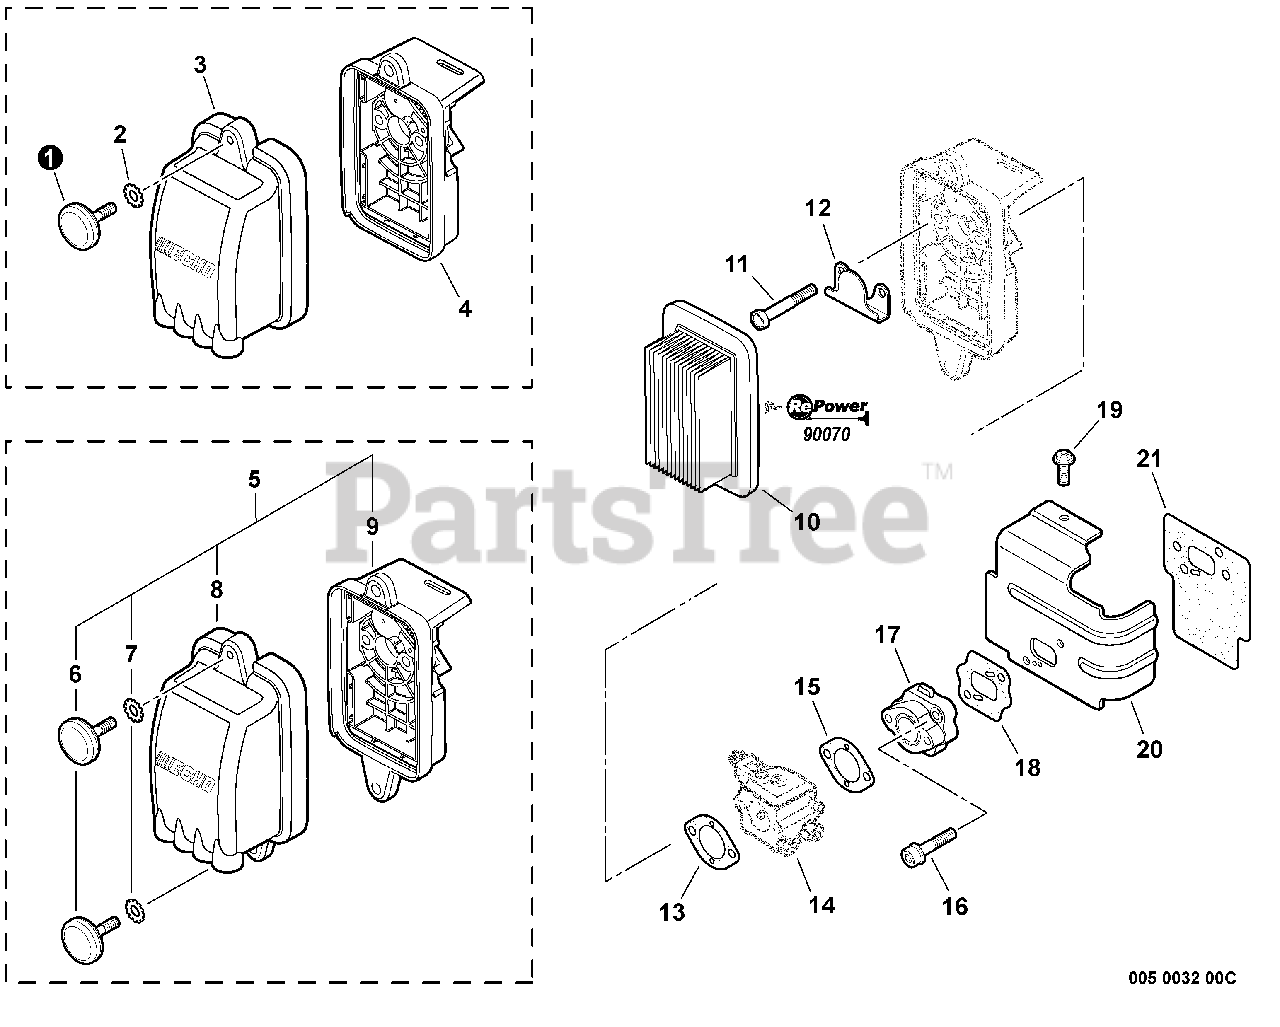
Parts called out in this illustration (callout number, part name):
1	THUMBSCREW
3	COVER, AIR FILTER
4	AIR FILTER CASE ASSY
5	FILTER KIT, AIR
6	THUMBSCREW
8	COVER, AIR FILTER
9	CASE ASSY, AIR FILTER
10	FILTER, AIR
11	BOLT 5×60
12	PLATE, PREVENT
13	GASKET, INTAKE
14	CARBURETOR
15	GASKET
16	INSULATOR, INTAKE
17	BOLT 5×25
18	GASKET, INTAKE
19	COVER, CYLINDER
20	SCREW 5×10
21	HEAT SHIELD, INTAKE
22	TUNE-UP KIT - REPOWER
